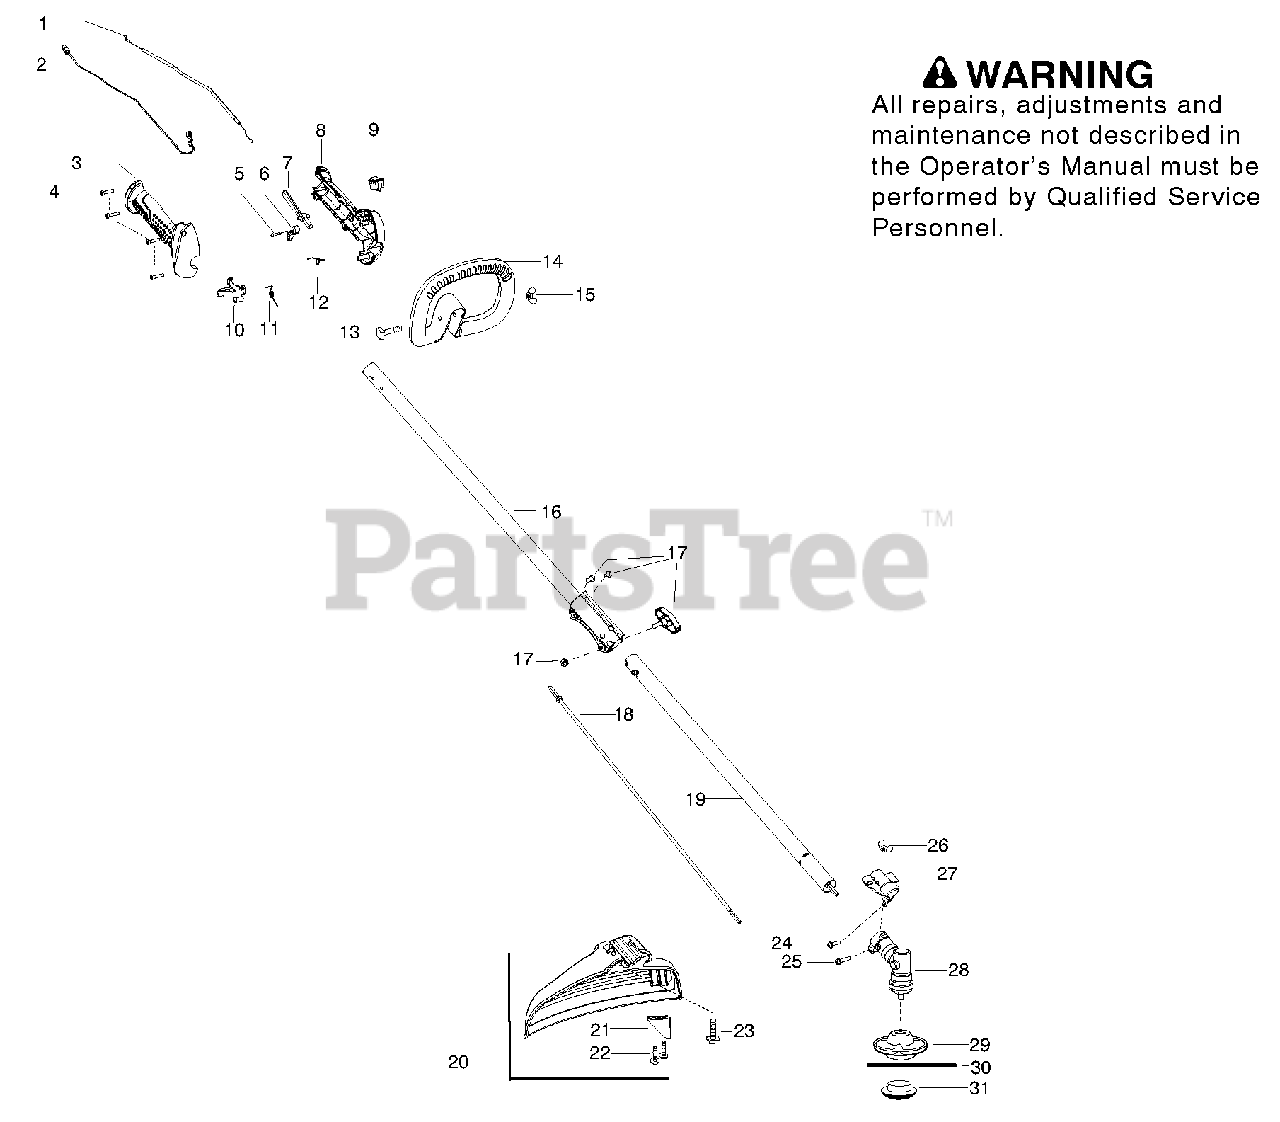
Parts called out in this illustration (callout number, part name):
1	Cable - Throttle (9010-gp0501)
2	Assembly - Switch Wire (9010-332103)
3	Housing - Throttle RH (9068-336202)
4	Screw (6sdabb04-12)
5	Screw - Lockout Arm
6	Arm - Lockout
7	Lockout (9176-336202)
8	Housing - Throttle LH (9068-336201)
9	Switch (9022-330522)
10	Trigger (9028-336201)
11	Spring - Trigger (9024-336203)
12	Spring - Lockout (9024-336202)
14	Assembly - Assist Handle
15	Wingnut
16	Kit - Upper Driveshaft
17	Kit - Knob/Screw
18	Flexshaft
19	Kit - Lower Driveshaft
20	Kit - Shield
21	Limiter - Line
26	Wingnut
27	Bracket - Shield
29	Assembly - Fixed Line Head
30	Accy. - Line
31	Cap - Fixed Line
